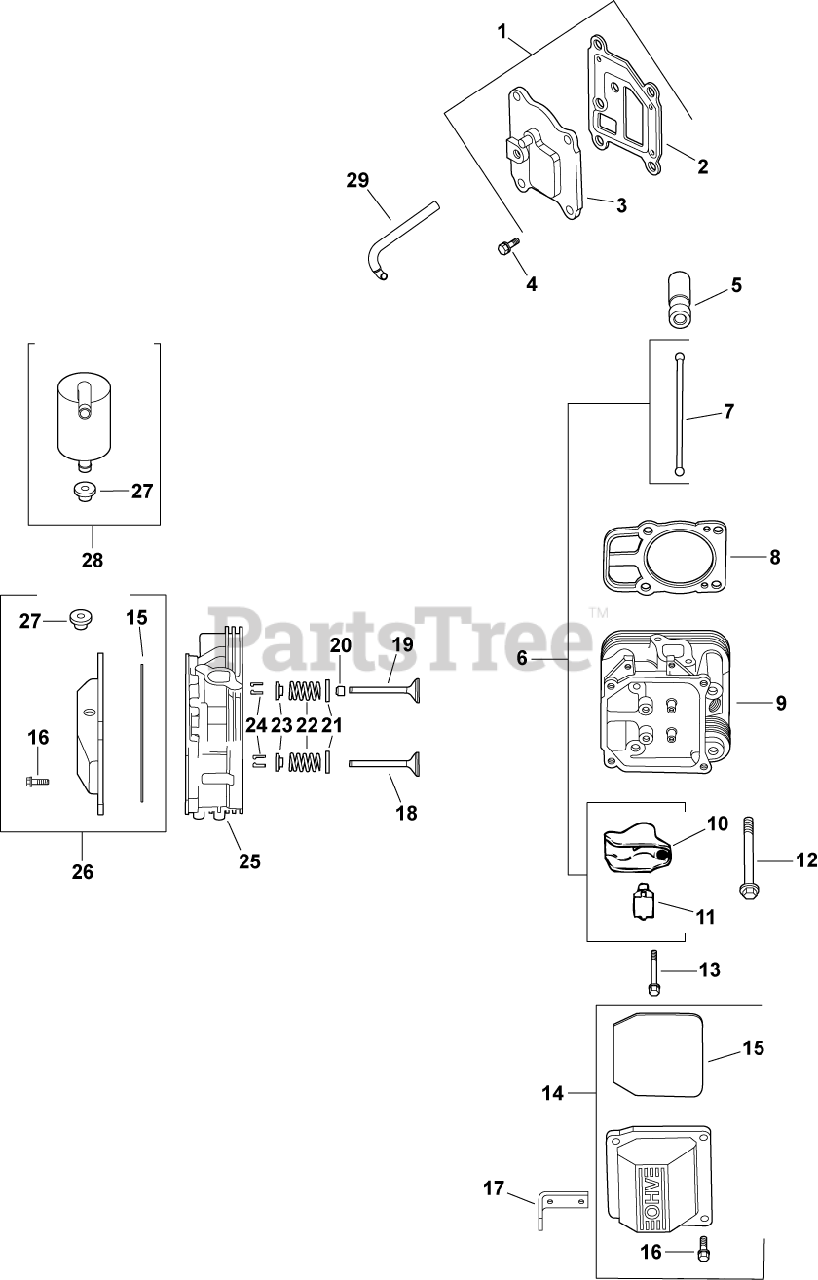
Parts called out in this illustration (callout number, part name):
1	KIT, BREATHER COVER W/GASKET
2	GASKET, BREATHER-USE 24 041 67-S
3	COVER, BREATHER -USE 24 096 125-S
4	SCREW,FLG THD FRM M6X1.0X20-(#25086396S)
5	LIFTER, HYDRAULIC VALVE-USE 25 351 10-S
6	KIT, VALVE TRAIN
7	ROD, PUSH
8	KIT, GSKT CYL HD (C22-23 674CC)
9	HEAD, ASSEM CYLINDER #2 -USE 24 318 113-
10	ARM, ROCKER
11	PIVOT, ROCKER ARM
12	SCREW - USE 62 086 08-S
13	SCREW, FLG M6X1.0X34
14	KIT, VALVE COVER-PLAIN
15	O-RING (YELLOW), VALVE COVER
16	SCREW, FLG M6X1.0X30
17	STRAP, LIFTING-USE 25 445 03-S
18	VALVE, EXHAUST (STD) - USE 32 016 01-S
19	VALVE, INTAKE (STD)
20	SEAL, VALVE STEM - (#2503214S)
21	RETAINER, SPRING
22	SPRING, VALVE
23	RETAINER, VALVE SPRING - USE 25 173 28-S
24	KIT, RETAINER
25	HEAD, ASSEM CYLINDER #1 -USE 24 318 105-
26	KIT, VALVE COVER
27	GROMMET, RUBBER
28	KIT, BREATHR SEPARATR-(#24755241S)
29	HOSE, BREATHER
2401602-S	VALVE, EXHAUST (.25)
2401702-S	VALVE, INTAKE (.25)
24755147-S	KIT, CYLINDER HEAD HARDWARE
